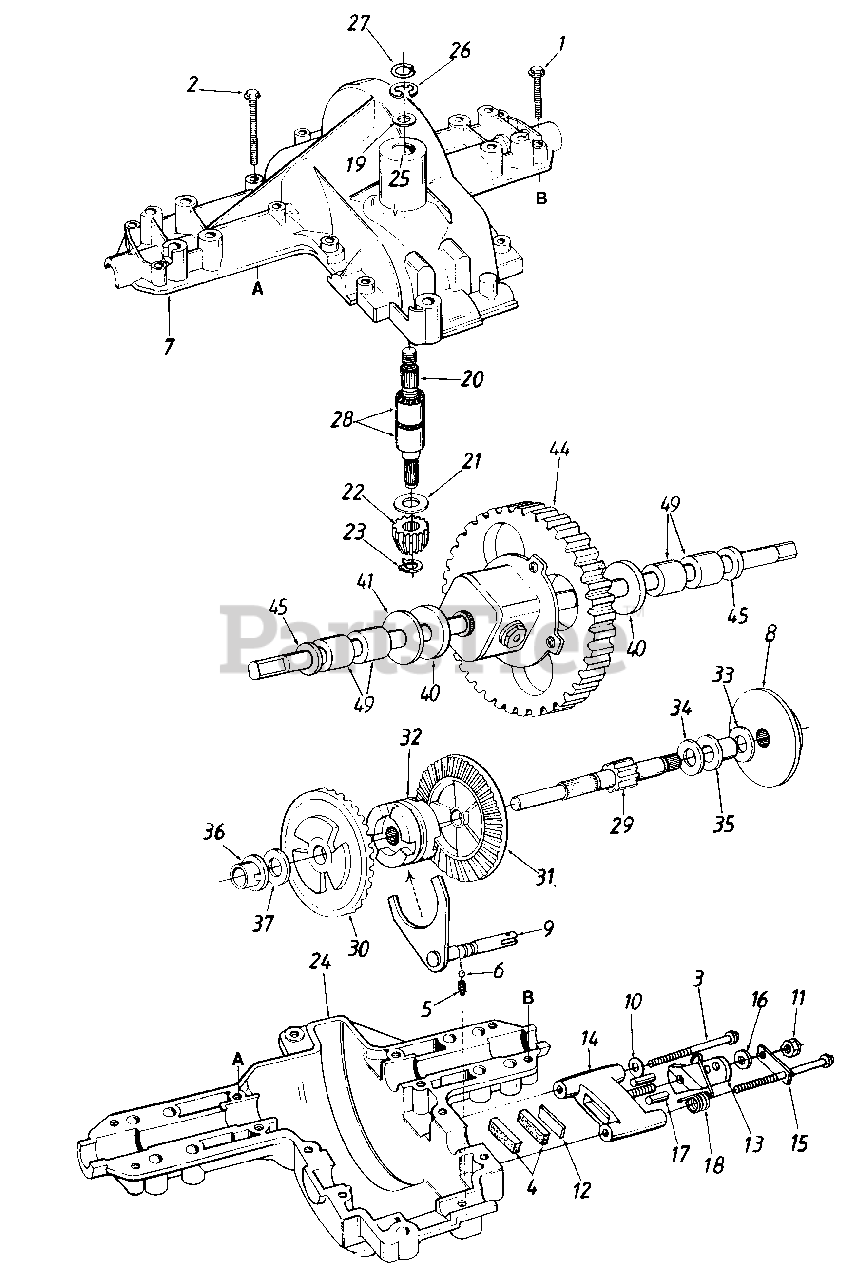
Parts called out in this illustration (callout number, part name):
1	Hex Wash. Hd. TT-Tap Scr. 1/4-20 x 1.25" Lg.
2	Hex Wash. Hd. TT-Tap Scr. 1/4-20 x 1.75" Lg.
3	Hex Wash. Hd. Tap Scr. 1/4-20 x 2.38" Lg.
4	Brake Puck
5	Spring Detent
6	Ball Detent
7	Upper Housing
8	Brake Disc
9	Shift Fork Ass'y.
10	FL-Wash. .312" I.D. x .75" O.D.
11	Hex Top L-Nut 5/16-24 Thd.
12	Puck Plate
13	Actuating Arm-L.H.
14	Brake Yoke
15	Anti Rotation Brkt.
16	FL-Wash. 11/32" I.D. x 7/8" O.D.
17	Actuating Pin
18	Torsion Spring
19	FL-Wash. 5/8" I.D. x 1" O.D. x .020" Thk.
19	FL-Wash. 5/8" I.D. x 1" O.D. x .030" Thk.
19	FL-Wash. 5/8" I.D. x 1" O.D. x .040" Thk.
20	Input Shaft
21	FL-Wash. 5/8" I.D. x 1.25" O.D.
22	Pinion Input 14T
23	Retaining Ring
24	Lower Housing
25	Oil Seal
26	"E"-Ring
27	Wire Ring
28	Needle Bearing
29	Drive Shaft-L.H. Brake
30	Bevel Gear 42T Small I.D.
31	Bevel Gear 42T Large I.D.
32	Clutch Collar
33	FL-Wash. 5/8" I.D. x 1" O.D. x .020" Thk.
33	Thrust Wash. 5/8" I.D. x 1" O.D. x .025" Thk.
33	FL-Wash. 5/8" I.D. x 1" O.D. x .030" Thk.
33	Thrust Wash. 5/8" I.D. x 1" O.D. x .035" Thk.
33	FL-Wash. 5/8" I.D x 1" O.D. x .040" Thk.
34	FL-Wash. .7" I.D. x 1.125" O.D.
35	Flanged Brg. 5/8" I.D. x 15/16" Lg.
36	Flanged Brg. 5/8" I.D. x 3/4" Lg.
37	Thrust Wash. 5/8" I.D. x 1" O.D. x .025" Thk.
37	FL-Wash. 5/8" I.D. x 1" O.D. x .030" Thk.
37	Thrust Wash. 5/8" I.D. x 1" O.D. x .035" Thk.
40	Axle Spacer
41	FL-Wash. .76" I.D. x 1.5" O.D. x .010" Thk.
41	FL-Wash. .76" I.D. x 1.5" O.D. x .020" Thk.
41	FL-Wash. .76" I.D. x 1.5" O.D. x .030" Thk.
41	FL-Wash. .76" I.D. x 1.5" O.D. x . 060" Thk.
44	Differential Ass'y.
45	Seal
49	Sleeve Brg. 3/4" I.D. x 1" Lg.
